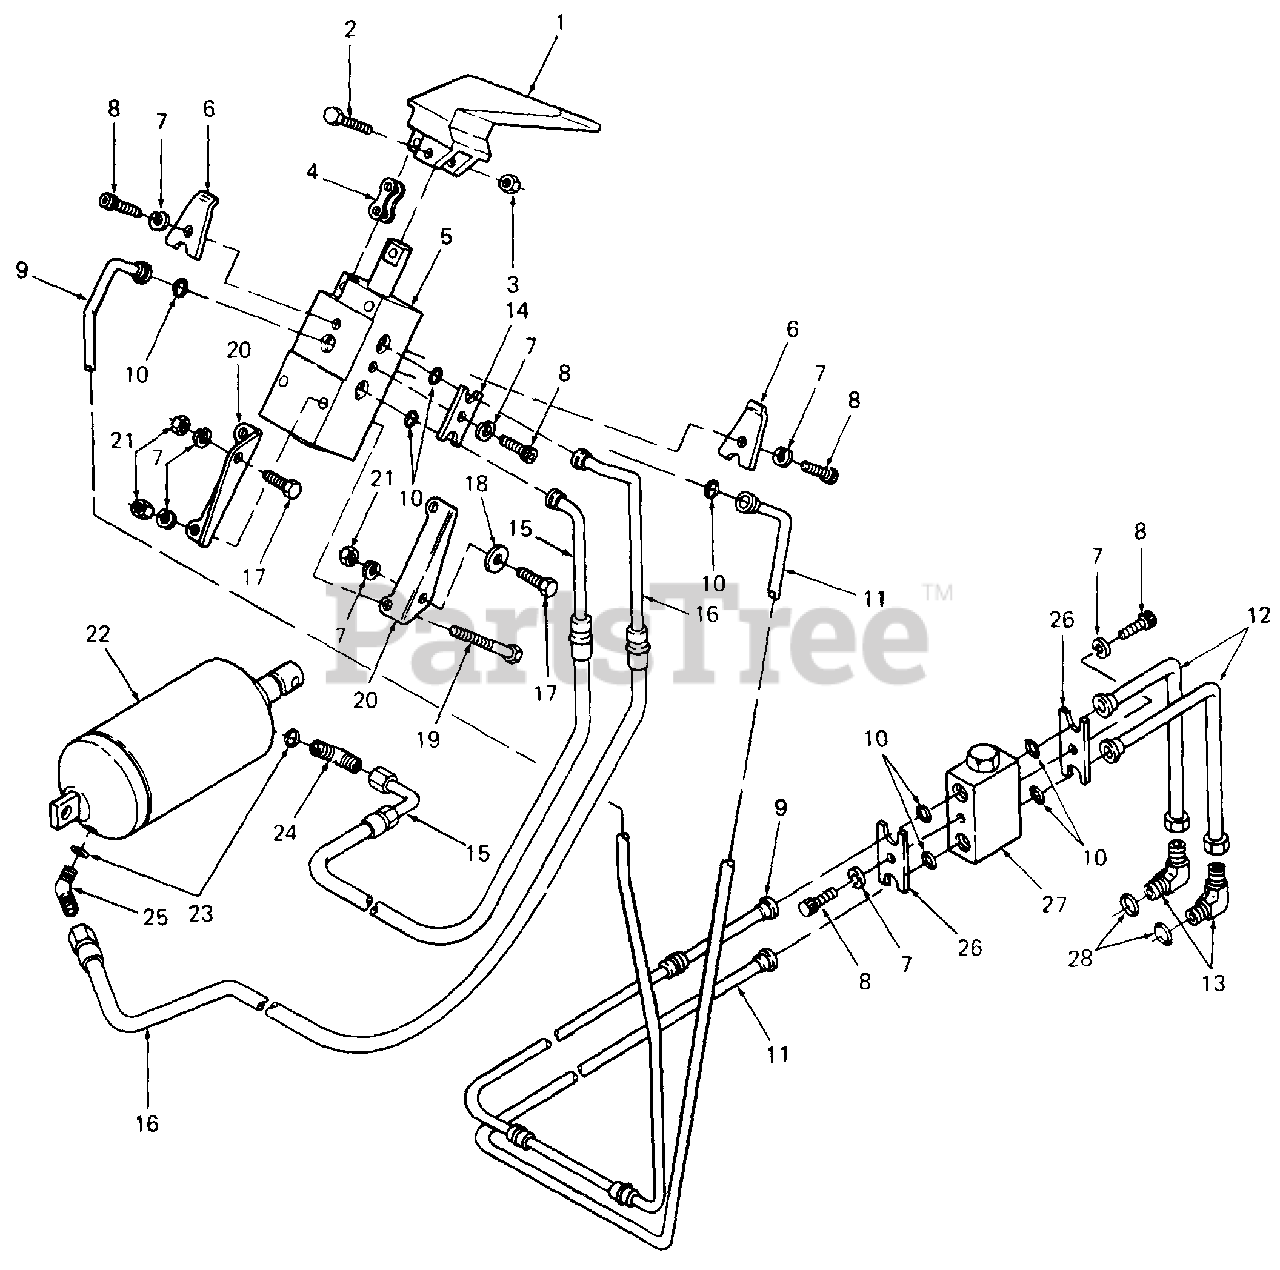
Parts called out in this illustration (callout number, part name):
1	Handle, Valve
2	Screw, Hex Cap, #10-24 X 1.0 Lg
3	Nut, Hex Center Lock, #10-24
4	Link, Chain
5	Valve Lift
6	Clamp, Single
7	Washer, Lock, 1/4
8	Screw, Socket Hd Cap, 1/4-20 X .62 Lg GR8
9	Tube Assy, Return
10	O-Ring, .301 X .070 Dia
11	Tube Assy, Pressure
12	Tube Assy, Adapter
13	Elbow, Tube, 90 Degree
14	Clamp, Double
15	Hose, Cylinder - Contracting
16	Hose, Cylinder - Extending
17	Screw, Hex Cap, 1/4-20 X .62 Lg GR5
18	Washer, Bell, .265 X .75 X .062 Thk
19	Screw, Hex Cap, 1/4-20 X 2.25 Lg
20	Bracket, Valve Mtg
21	Nut, Hex, 1/4-20 GR5
22	Cylinder, Hydraulic
23	O-Ring, 1/4 OD Tube
24	Elbow, 90 Degree w/O-Ring
25	Elbow, 45 Degree w/O-Ring
26	Clamp, Valve Side
27	Valve, Relief
28	O-Ring, 3/8 OD Tube
